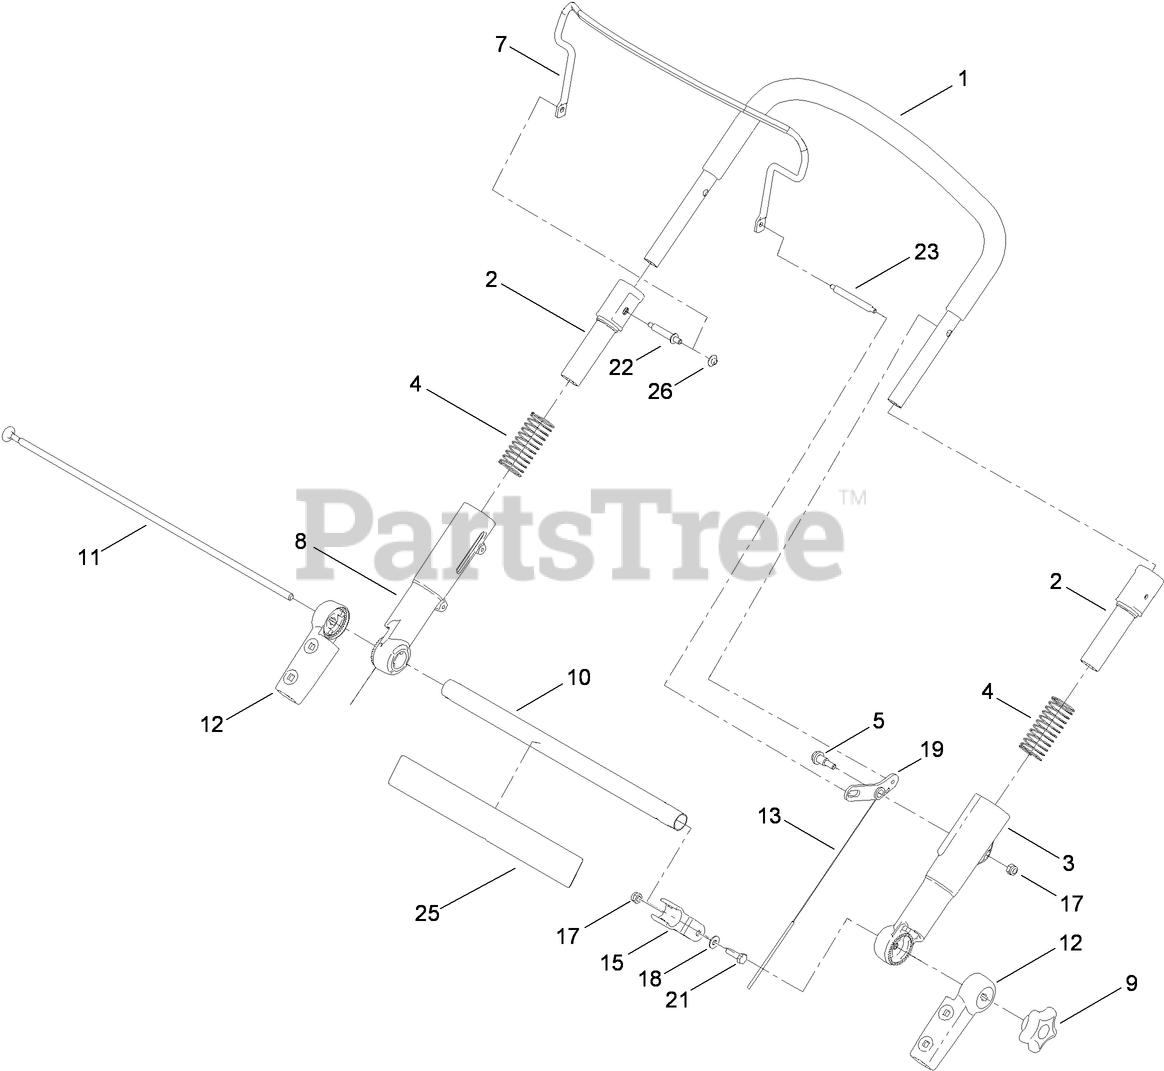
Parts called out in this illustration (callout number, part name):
1	UPPER HANDLE ASM
2	SLEEVE-INNER
3	SLEEVE-OUTER, LH
4	SPRING-COMPRESSION
5	BOLT-SHOULDER
7	BAIL-BRAKE
8	SLEEVE-OUTER, RH
9	KNOB-HANDLE
10	TUBE-CROSS
11	ROD-THREADED
12	MOUNT-HANDLE, LOWER
13	CABLE-TRACTION
15	CLAMP-CABLE
17	NUT-LOCK, NI
18	WASHER-FLAT
19	LEVER-TRACTION
21	SCREW-HH
22	PIN-HANDLE
23	PIN-HANDLE, BBC
25	DECAL-ADS
26	RETAINER-PUSH ON
